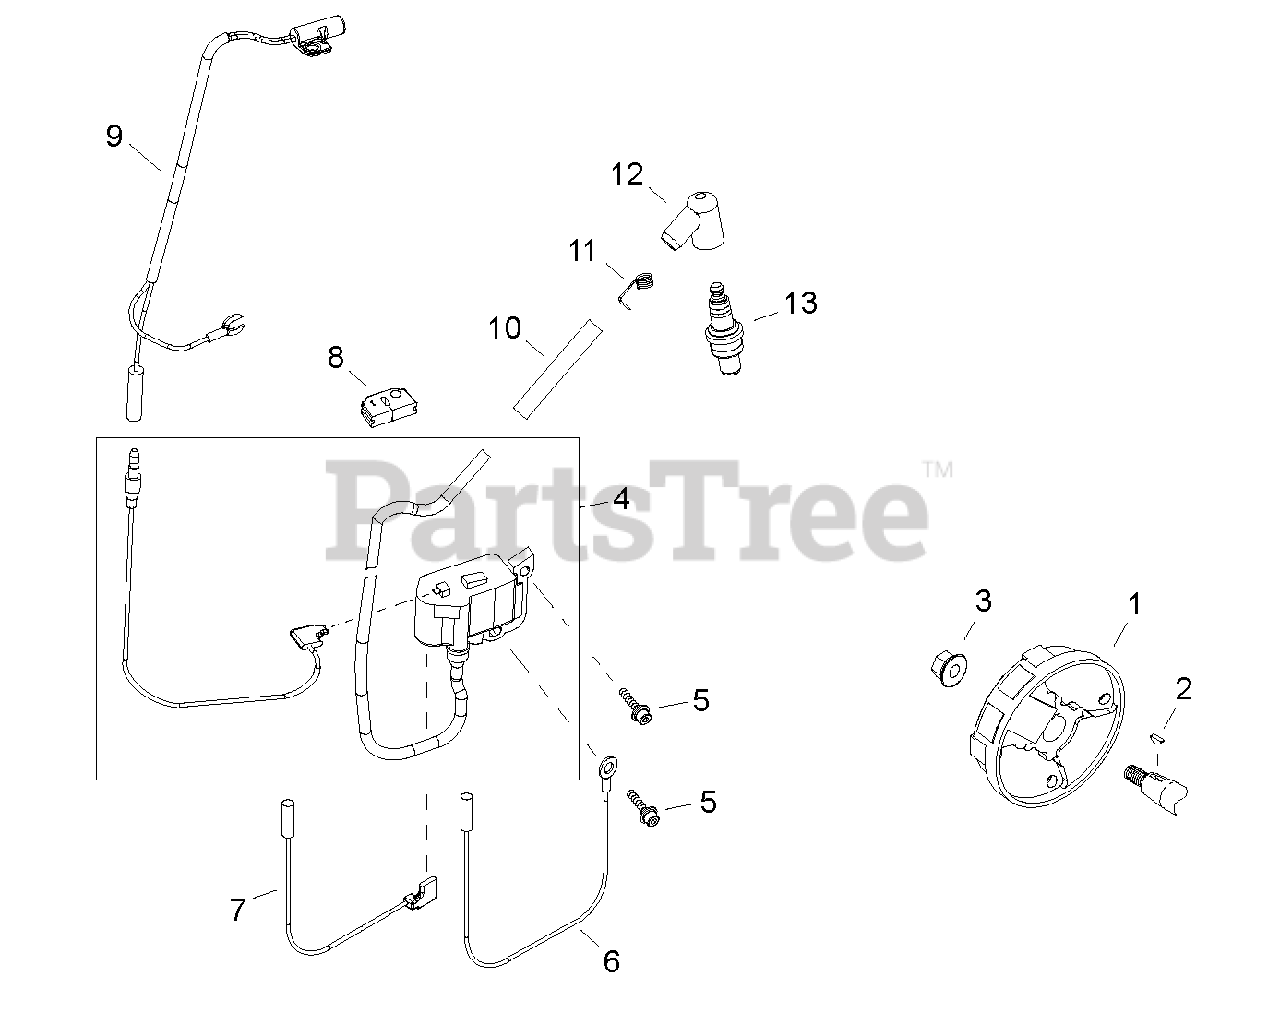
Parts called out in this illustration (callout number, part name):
1	FLYWHEEL
2	KEY - 3X10
3	NUT - 8
4	IGNITION COIL ASSY
5	SCREW - 4X20
6	LEAD - GROUND
7	LEAD - IGNITION
8	GROMMET
9	SENSOR, THERMAL
10	TUBE
11	TERMINAL, SPARK PLUG CAP
12	CAP, SPARK PLUG
13	SPARK PLUG -- CMR-5H
